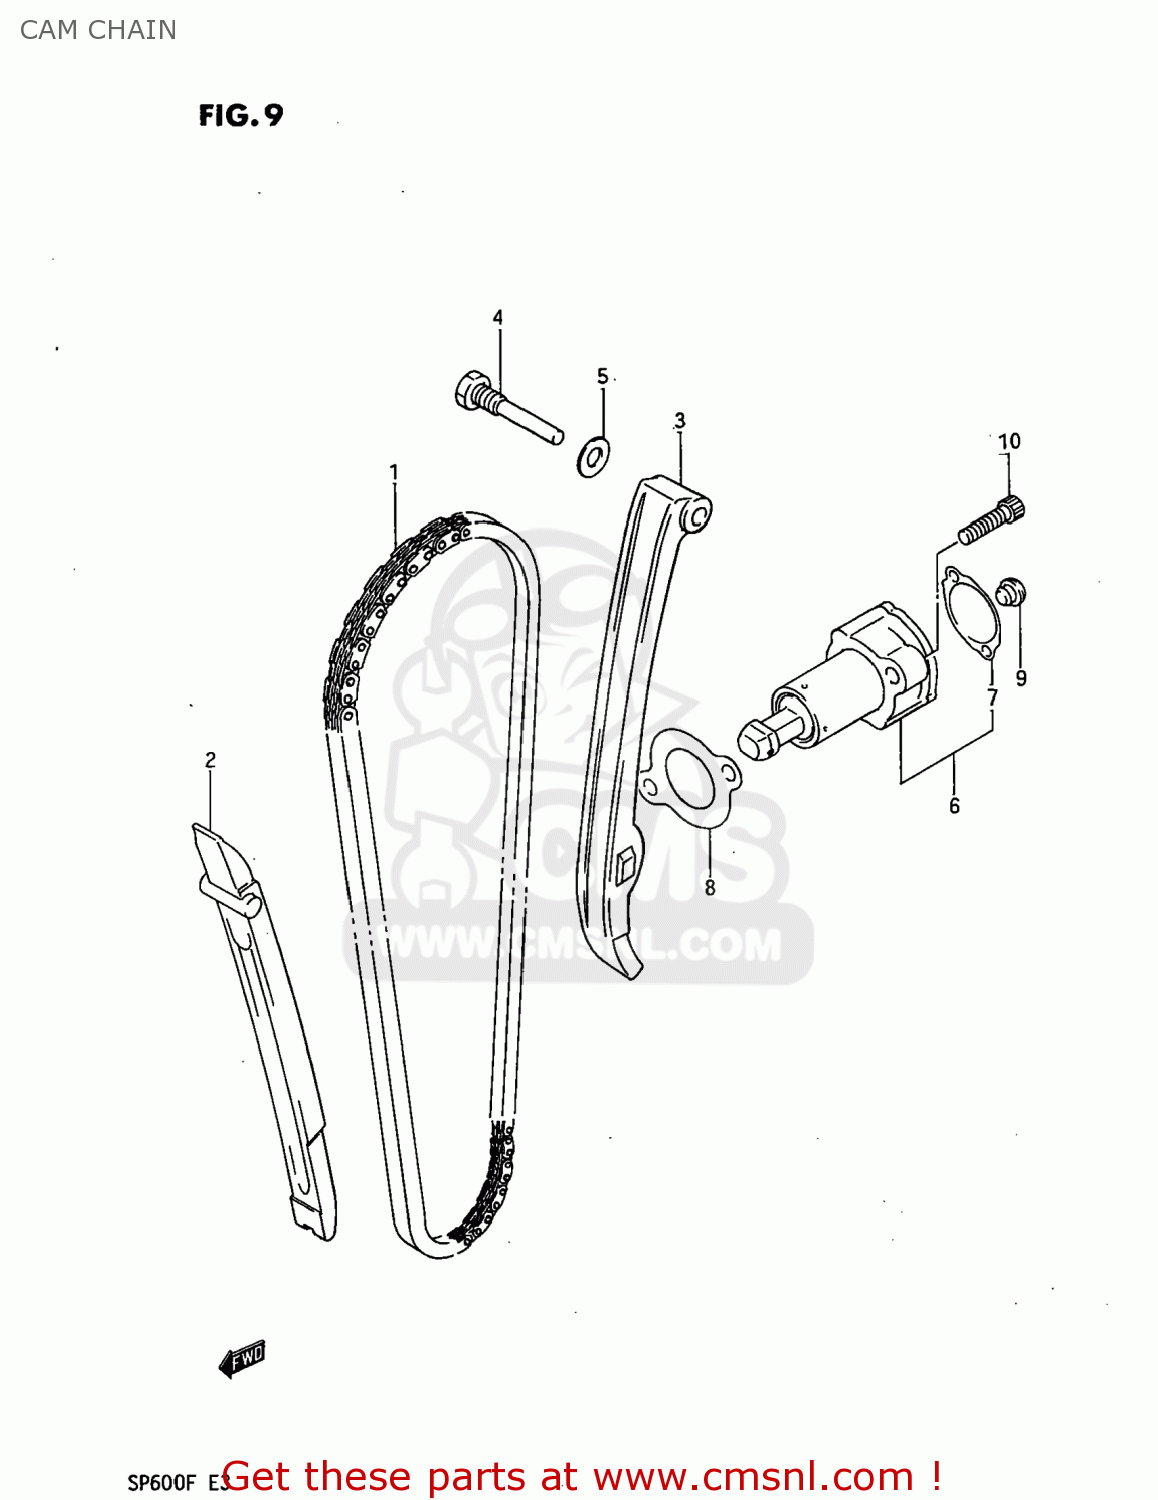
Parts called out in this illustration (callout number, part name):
1	CHAIN,CAMSHAFT DRIVE
2	GUIDE,CAM CHAIN
3	TENSIONER,CAM CHAIN
4	BOLT,CAM CHAIN TENSIONER
5	GASKET 8.2X14X1 (NAS)
6	ADJUSTER ASSEMBLY,TENSIONER
7	GASKET,ADJUSTER CAP (MCA)
8	GASKET,TENSIONER ADJUSTER (MCA)
9	PLUG,ADJUSTER
10	BOLT
